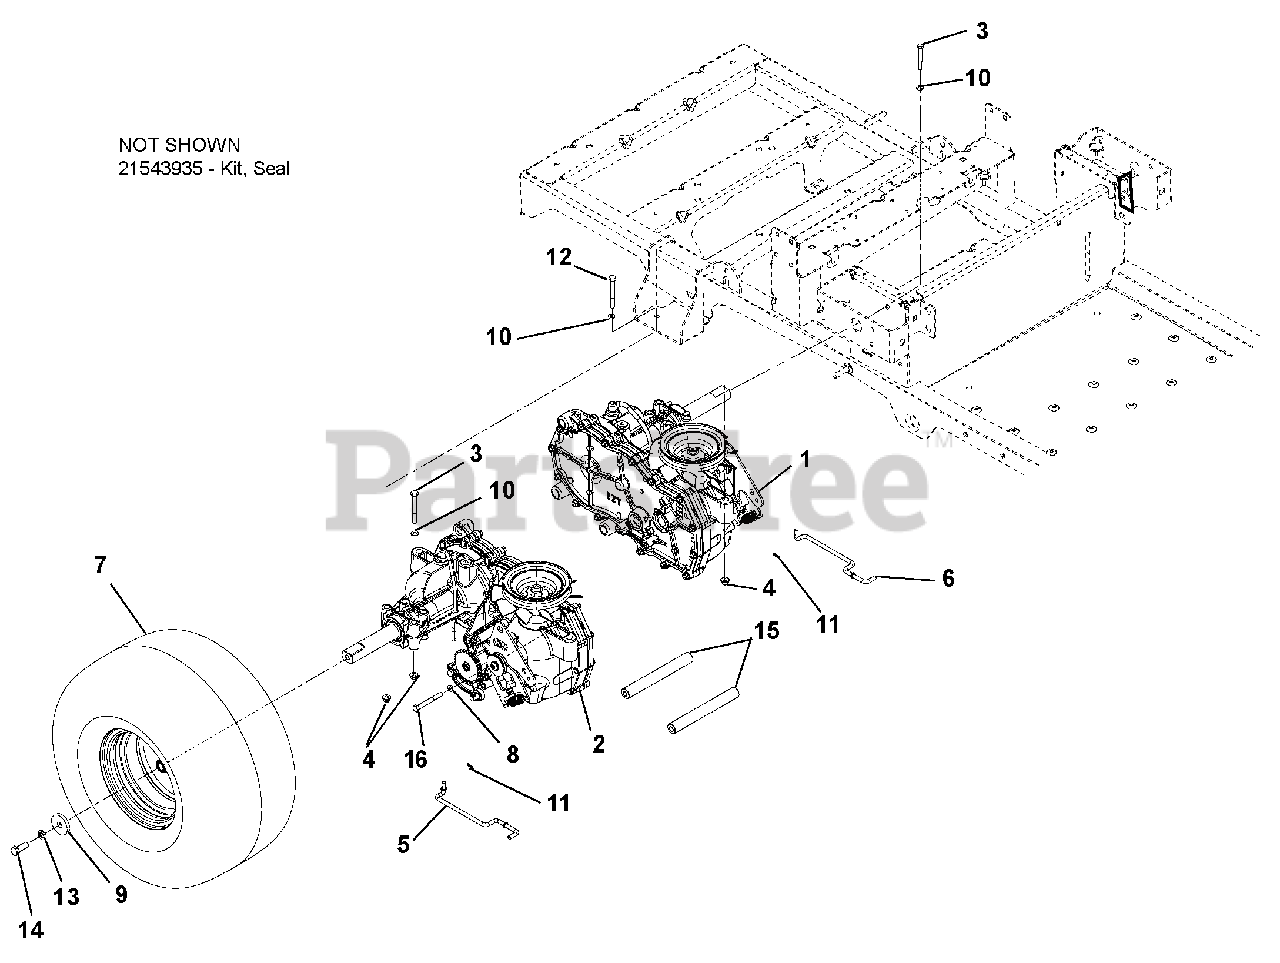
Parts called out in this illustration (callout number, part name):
1	Transaxle, Left Hand EZT D-Shaft (915146, 168)
2	Transaxle, Right Hand EZT D-Shaft (915146, 168)
3	Bolt, Hex .31-18 x 2.25
4	Nut 5/16-18 Flange Nyloc
5	Dump Valve, Right Hand
6	Dump Valve, Left Hand
7	Tire Assembly 18 x 6.5-8 2 Ply DSHAFT (915146, 168)
8	Washer, Flat Steel .406 x 1.00 x .188
9	Washer, Flat Steel .406 x 1.50 x .245
10	Washer, Flat Steel .38 x .875 x .083
11	Pin, Hair, Internal .06 x .18 x .77
12	Bolt, Hex .31-18 x 2.75
13	Washer, Locking .38 x .094 Regular
14	Bolt, Hex .38-16 x 1.00 YWZC EP30
15	Shaft, Transaxle Brace
16	BOLT, HEX .38-16 X 2.50
